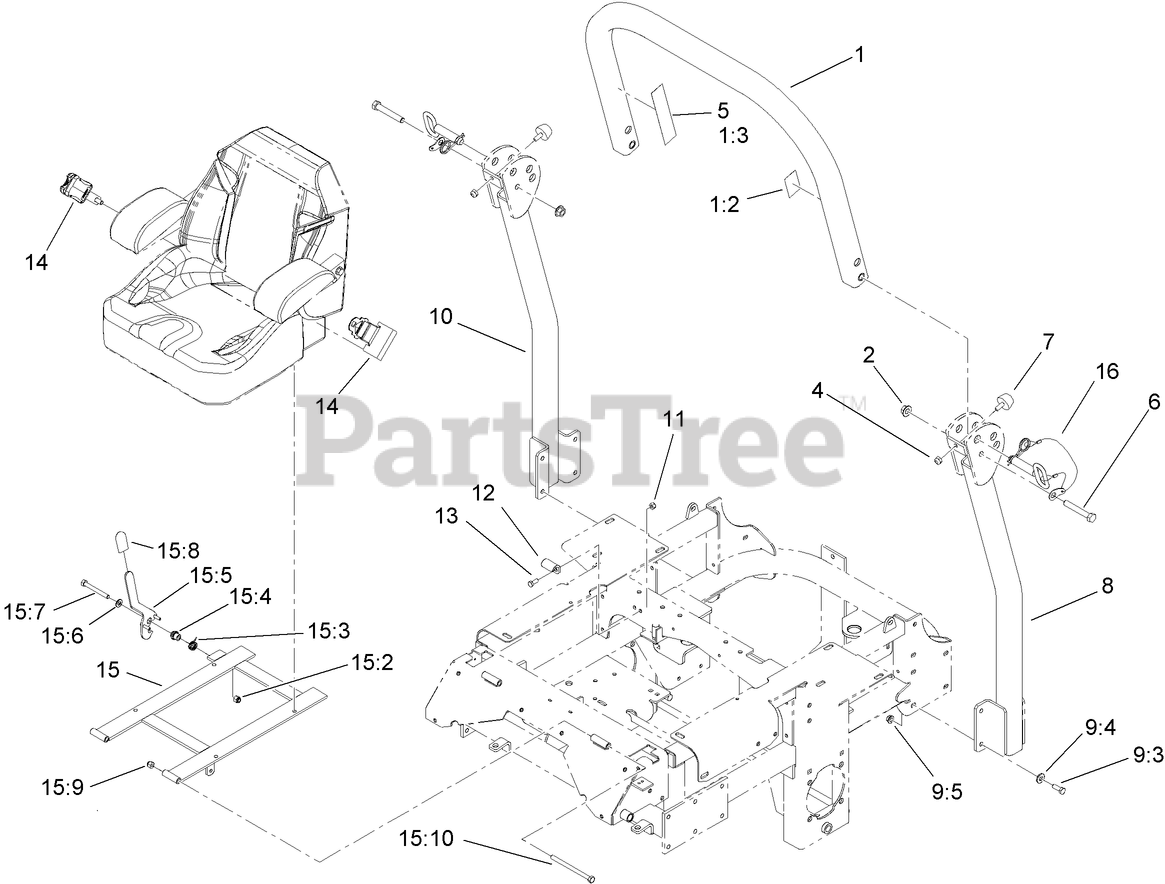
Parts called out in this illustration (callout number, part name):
1	Upper Tube ASM
1:2	DECAL-ROPS
1:3	DECAL-WARNING, FOLDING ROPS
2	NUT-HF
4	NUT-LOCK, NI
5	DECAL-WARNING
6	SCREW-HH
7	BUMPER-RUBBER
8	TUBE-SUPPORT, LH
9	BAG-BOLT, ROPS
9:3	SCREW-HH
9:4	WASHER-BELLEVILLE
9:5	NUT-HHF, WHIZ
10	TUBE-SUPPORT, RH
11	NUT-LOCK, NI
12	Catch-Latch, Seat
13	SCREW-HH
14	SEAT BELT KIT
15	SEATFRAME ASM
15:2	NUT-LOCK, NI
15:3	SPRING-TORSION
15:4	BUSHING-LATCH, SEAT
15:5	LATCH ASM
15:6	WASHER-FLAT
15:7	SCREW-HH
15:8	GRIP-LEVER
15:9	NUT-LOCK, NI
15:10	SCREW-HH
16	PIN-FOLD, ROPS
